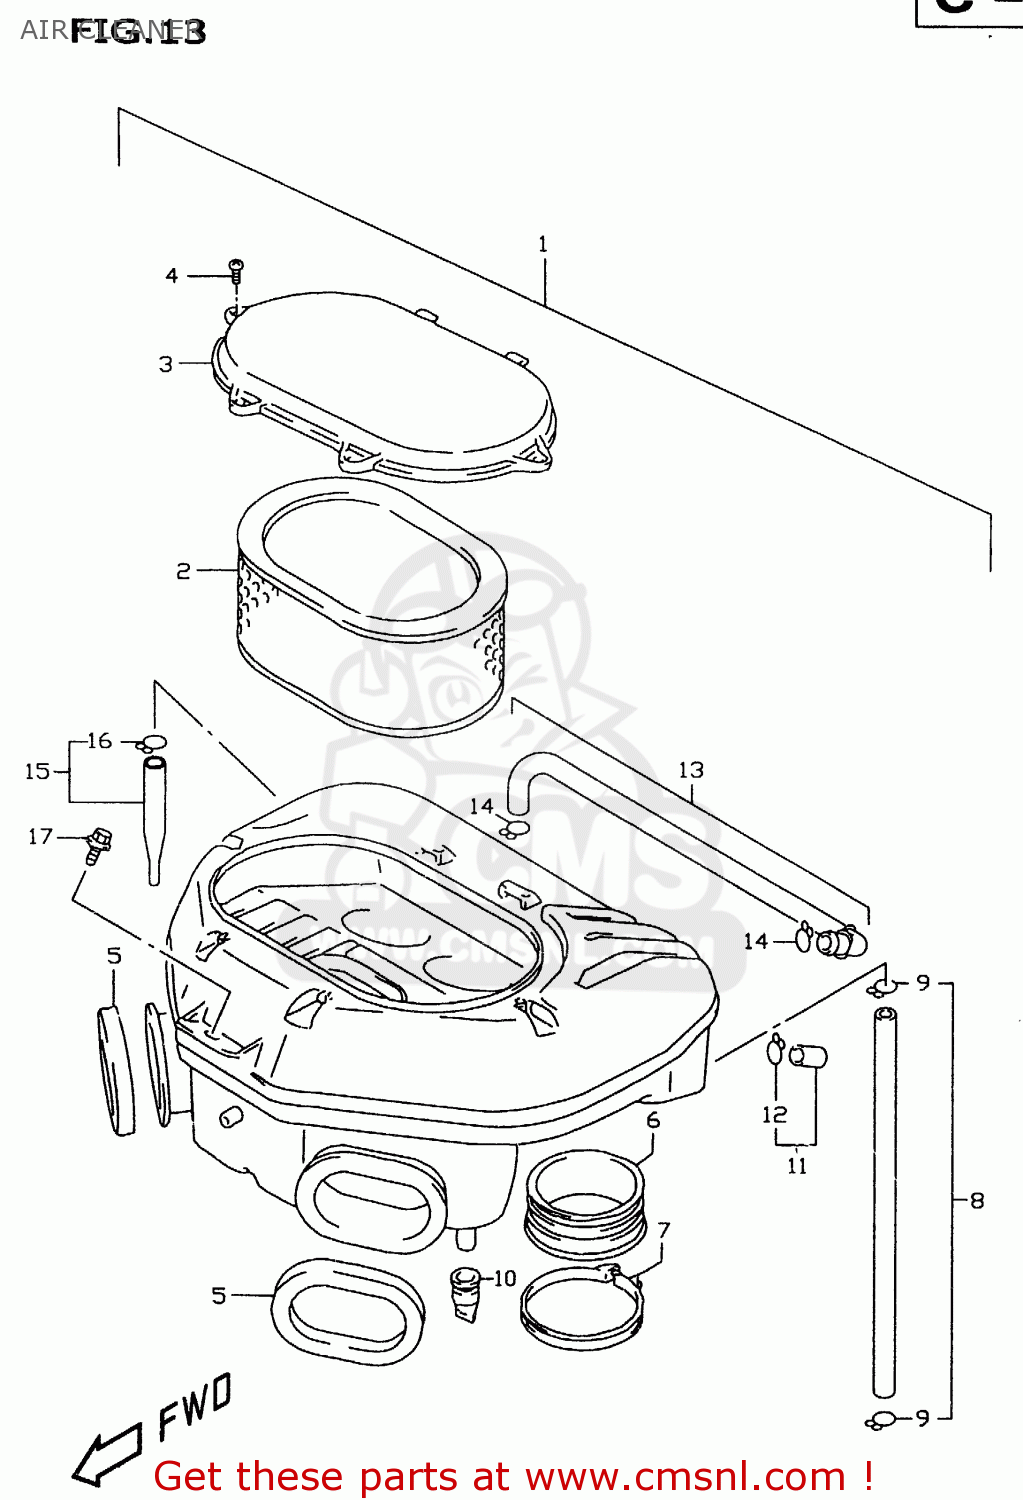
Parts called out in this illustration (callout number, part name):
1	CLEANER ASSY,AIR
2	FILTER,AIR CLEANER
3	CAP,AIR CLEANER
4	SCREW 5X12
5	CUSHION,DUCT
6	TUBE,OUTLET
7	CLAMP
8	TUBE,BREATHER
9	CLIP
10	CAP,DRAIN
11	PLUG
12	CLIP
13	TUBE,SECOND AIR
14	CLIP
15	TUBE,CONTROLL AIR
16	CLIP
17	BOLT
